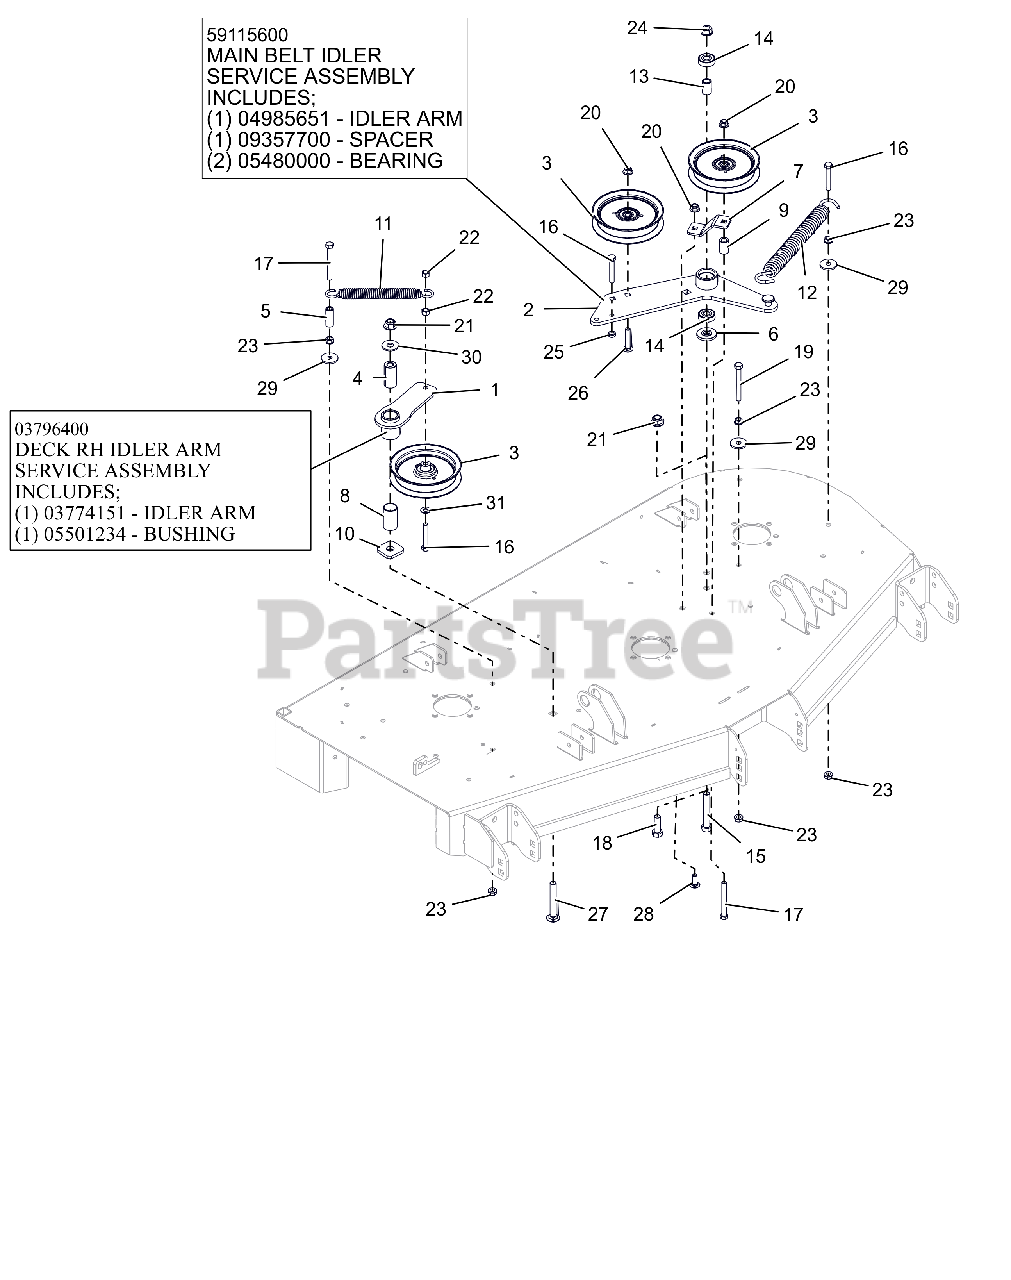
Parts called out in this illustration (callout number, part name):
1	WMT, IDLER ARM - BLACK
1	ASM, IDLER ARM (DECK)
2	DECK PTO IDLER ARM WLDMT - BLK
2	ASSEMBLY, MAIN BELT IDLER
3	IDLER, FLAT 5.00"
4	BSHG, SPCR .502X.997X2.03 PM
5	SPACER, .375IDX.625ODX1.66 PM
6	SPACER, IDLER ARM
7	PTO FIXED IDLER MTG BRKT -RED
8	BSHG, 1.00X1.125X1.937
9	BUSHING, SLV .380X.750X1.190
10	WSHR-FLT .640X1.75X.250
11	SPRING, EXTENSION
12	SPRING, EXTENSION
13	SPACER .510 X .75 X 1.1485
14	BRG-BALL .500X1.38X.437
15	BLT, HEX .50-13X3.00 G5 ZCC
16	BLT,HEX .38-16X2.25 G5 ZCC
17	BLT, HEX .38-16X3.25 G5 ZCC
18	BLT,HEX .50-13X1.50 G5 ZCC
19	BLT, HEX .38-16X3.25 G5 ZCC
20	NUT,NYL-FLG .38-16 GF ZCC
21	NUT,NYL-FLG .50-13 GF ZCC
22	NUT-LK-CTR .38-16 ZC120
23	NUT, SPNLK-FLG .38-16 G5 ZCC
24	NUT-LK-CTR-FLG .500-13 GG ZCC
25	NUT-JAM .375-16 G2 ZCC
26	BLT,RHSSN.375-16X2.00 G5 ZCC
27	BLT, RHSN .50-13X3.50 G5 ZCC
28	BLT,RHSSN .38-16X1.00 G5 ZCC
29	WSHR,FLT .406X1.375X.135 ZCC
30	WSHR,FLT .563X1.375X.109 ZCC
31	WSHR,FLT .406X.812X.065 ZCC
